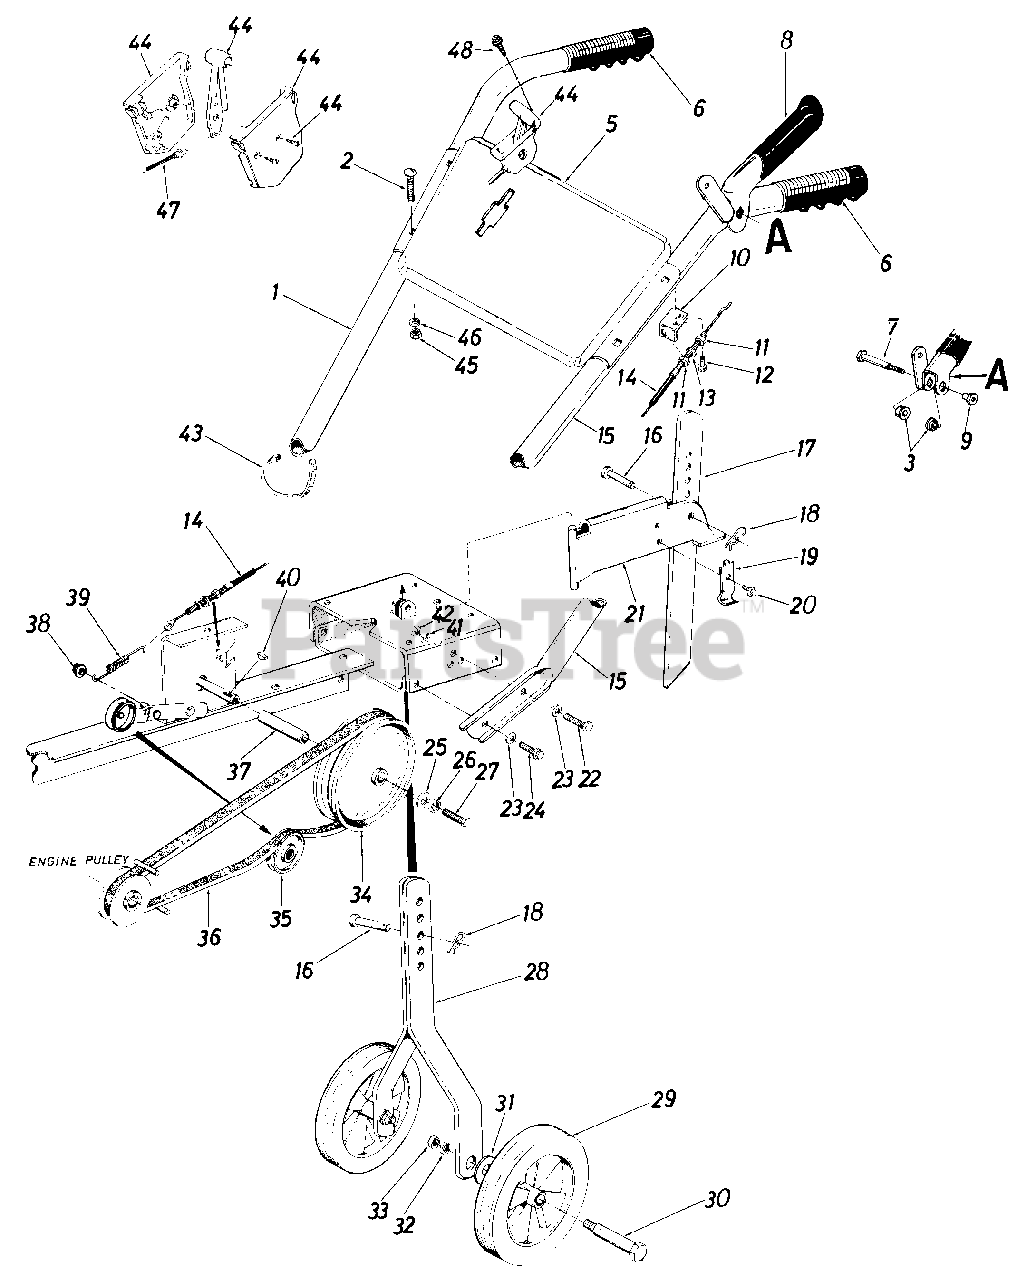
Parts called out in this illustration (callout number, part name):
1	Handle-R.H.
2	Carriage Bolt 5/16-18 x 1.75" Lg.
3	Hex Flange Plastic Brg.
5	Handle Panel
6	Grip
7	Shld. Bolt .38" Dia. x 1.53" Lg.
8	Clutch Grip Ass'y.
9	Shld. Nut 1/4-20 Thd.
10	Cable Support Brkt.
11	Hex Jam Nut 5/16-24 Thd.
12	Hex Wash. Hd. Self-Tap Scr. 1/4-20 x .50" Lg.
13	L-Wash. 5/16" I.D.
14	Clutch Control Cable
15	Handle-L.H.
16	Clevis Pin
17	Depth Bar
18	Hairpin Cotter
19	Depth Bar Spring
20	Hex Wash. Hd. Self-Tap Scr. 1/4-20 x .50" Lg.
21	Tailpiece Ass'y.
22	Hex Scr. 3/8-16 x 1.00" Lg.
23	Belleville Wash. 3/8" I.D.
24	Hex Wash. Hd. Self-Tap Scr. 3/8-24 x 7/8" Lg.
25	Fl-Wash. .25/ I.D. x .930" O.D. x .120" Thk.
26	L-Wash. 1/4" I.D.
27	Hex Scr. 1/4-28 x .75" Lg.
28	Wheel Bracket Ass'y.
29	Wheel Ass'y. 9 x 1.75
30	Shld. Bolt
31	Belleville Washer 1/2" I.D.
32	L-Wash. 1/2" I.D.
33	Hex Nut 1/2-20 Thd.
34	Pulley 6.00" O.D.
35	Idler Pulley
36	V-Belt 1/2" Pitch x 39"
37	Spacer
38	Cap Speed Nut
39	Extension Spring
40	Hi-Pro Key
41	L-Wash. 3/8" I.D.
42	Hex L-Nut 3/8-16 Thd.
43	Cable Ties
44	Throttle Control Box
45	Hex Nut 5/16-18 Thd.
46	L-Wash. 5/16" I.D.
47	Throttle Control Wire-35"
48	Self-Tap Scr. #10 x 1/2" Lg.
